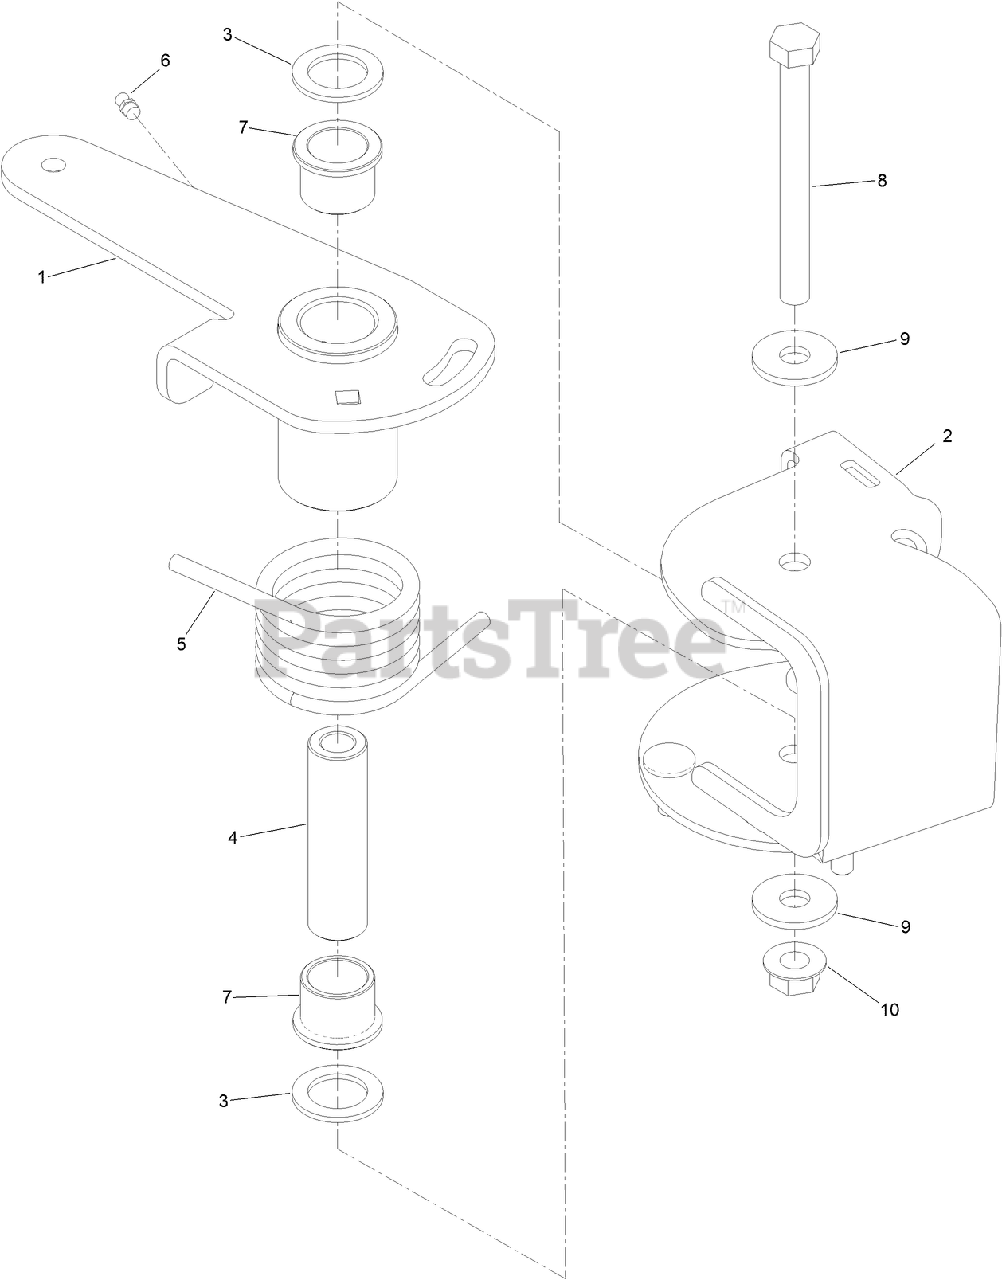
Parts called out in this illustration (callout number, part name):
1	ARM-IDLER
2	PIVOT-IDLER
3	SPACER-HARDENED
4	SPACER-PLAIN
5	SPRING-TORSION
6	FITTING-GREASE
7	BUSHING-FLANGE
8	SCREW-HH
9	WASHER-SUPPORT
10	NUT-HF
